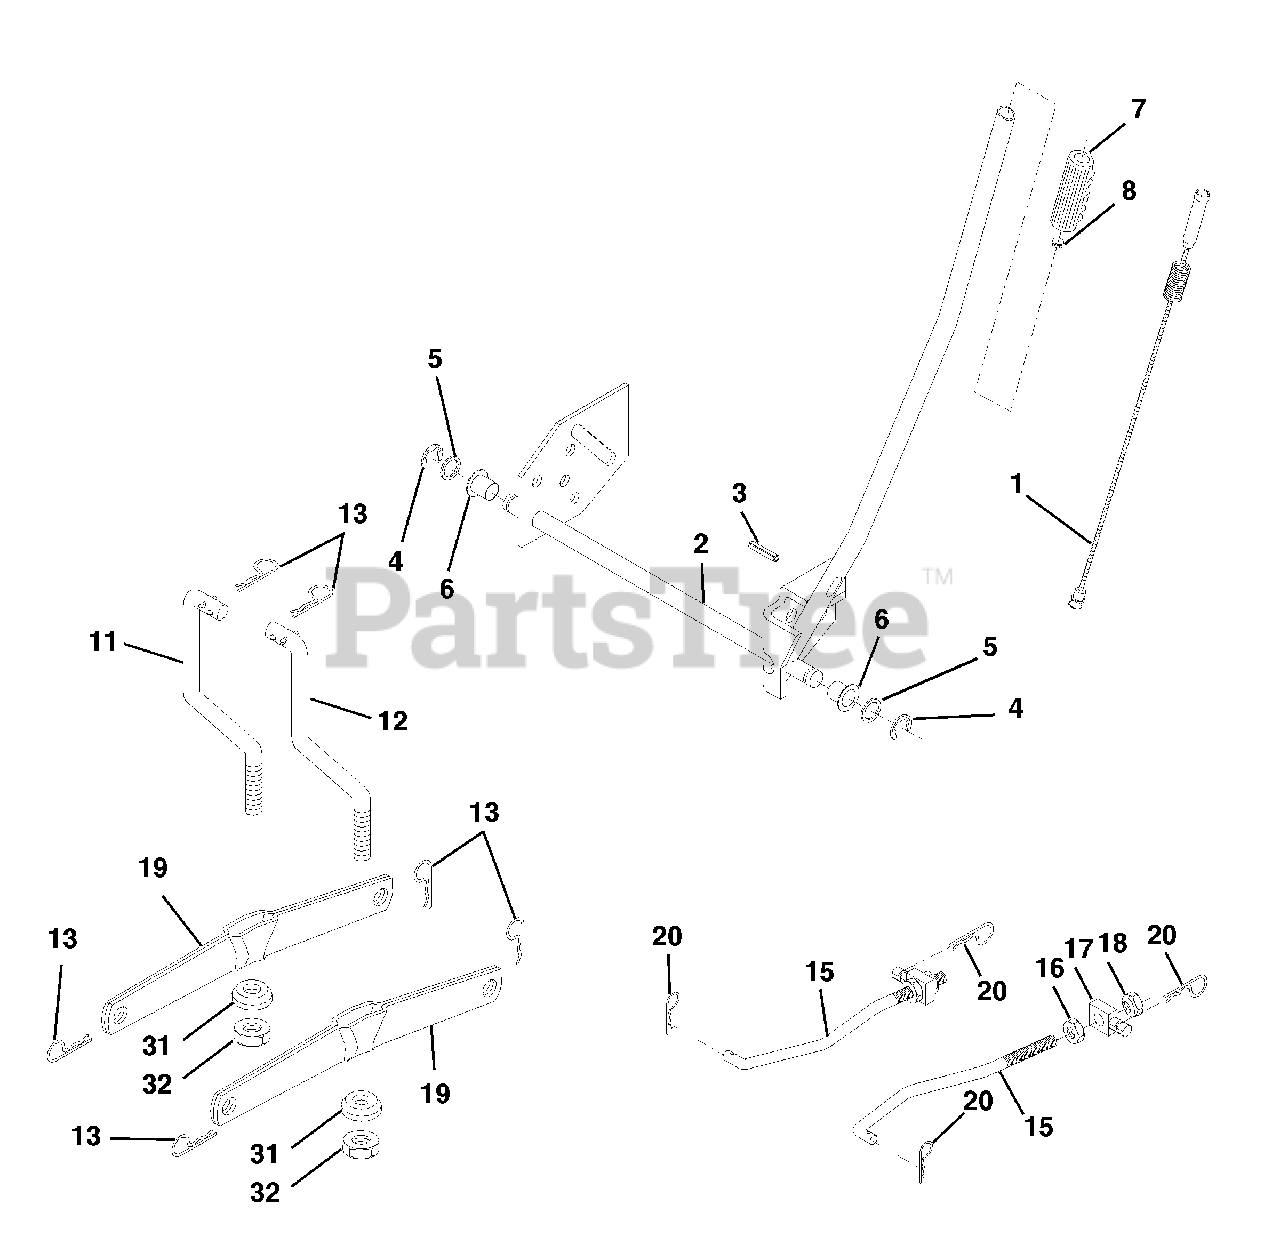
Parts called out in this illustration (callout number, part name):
1	Wire Asm Inner W/plunger LT
2	Shaft Asm Lift
3	Pin Groove
4	E-Ring #5133-62
5	Washer PLTD 21/32 X 1 X 21 ga
6	Bearing Nylon Blk 629 Id
7	Grip Handle Bicycle
8	Button Plunger Black
11	Link Lift LH
12	Link Lift RH
13	Retainer Spring
15	Link Front
16	Nut Jam Hex 1/2-13 Unc
17	Trunnion Blk Zinc
18	Nut Lock W/wsh 1/2-13unc
19	Arm Suspension Rear
20	Spring, Retainer
31	Bearing Pvt. Lift Spherical
32	Nut Crownlock 3/8-24
